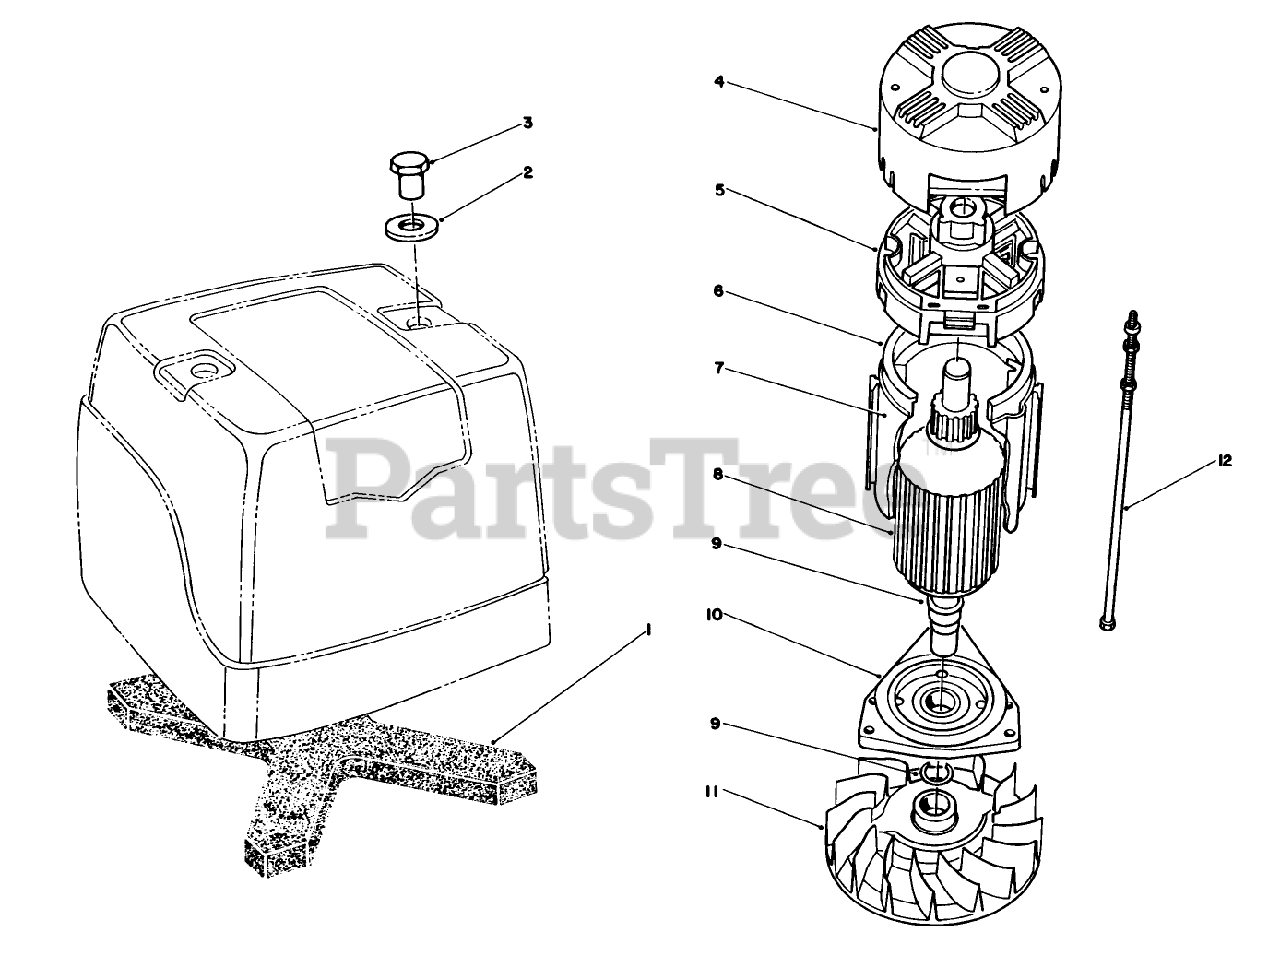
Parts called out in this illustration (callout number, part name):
1	Filter
2	Washer
3	Nut-Hex
4	End Cap-Brush
5	Brush Box Group (Includes: 490834 Brush Pin Group)
6	Housing Assembly
7	Insulator Group-Housing
8	Armature Group
9	Ring-Retaining
10	Spacer
12	Bolt-Thru (Includes Two Sets)
